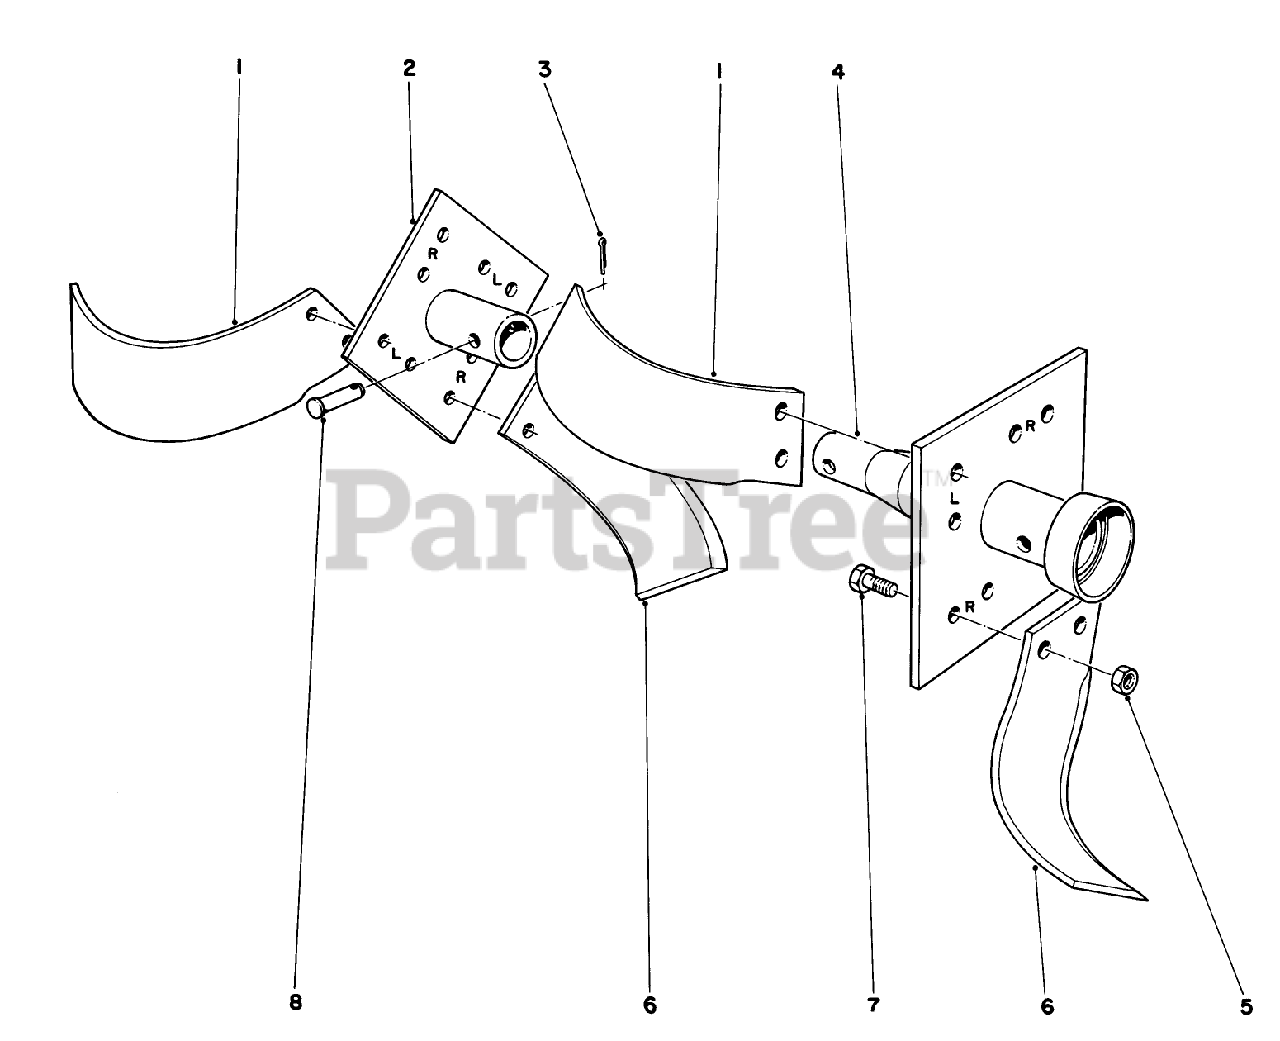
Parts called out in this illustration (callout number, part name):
1	Slasher Tine L.H.
2	Outer Axle R.H.
3	PIN-COTTER
4	Axle R.H.
5	NUT-LOCK, CONE
6	Tine R.H.
7	SCREW-HH
8	TINE PIN
